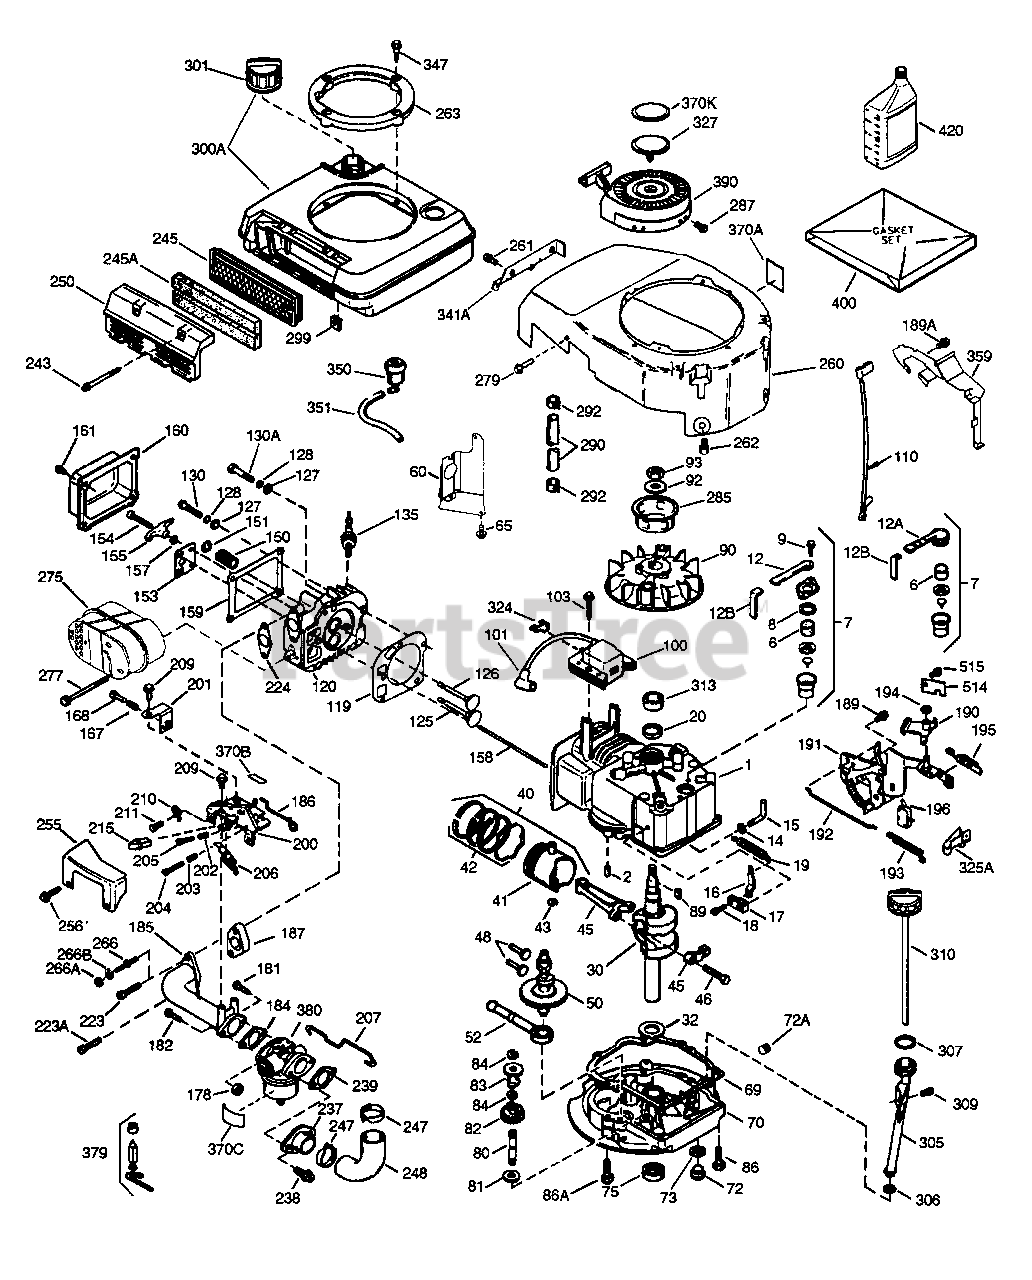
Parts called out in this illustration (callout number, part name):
1	"Cylinder (Incl. 2 & 20)
2	Dowel Pin
6	Breather Element
7	Breather Ass'y. (Incl. 6 & 12A)
12A	Breather Cover & Tube
14	Flat Washer
15	Governor Rod (Incl. 14)
16	Governor Lever
17	Governor Lever Clamp
18	Screw, Torx T-15, 8-32 x 19/64"
19	Extension Spring
20	Oil Seal
30	Crankshaft
40	Piston, Pin & Ring Set (Std.)
40	Piston, Pin & Ring Set (.010" OS)
41	Piston & Pin Ass'y. (Std.)
41	Piston & Pin Ass'y. (.010" OS) Incl. 43
42	Ring Set (Std.)
42	Ring Set (.010" OS)
43	Piston Pin Retaining Ring
45	Connecting Rod Ass'y. (Incl. 46)
46	Connecting Rod Bolt
48	Valve Lifter
50	Camshaft (MCR)
52	Oil Pump Ass'y.
60	Blower Housing Extension
65	Screw, 10-24 x 3/8"
69	* Mounting Flange Gasket
70	Mounting Flange (Incl. 72 thru 83)
72	Oil Drain Plug
75	Oil Seal
80	Governor Shaft
82	Governor Gear Ass'y. (Incl. 81)
83	Governor Spool
86	Screw, 1/4-20 x 1-7/32"
86A	Screw, 1/4-20 x 1/1/4"
89	Flywheel Key (also available in Packa ged Part #740007B)
90	Flywheel
92	Belleville Washer
93	Flywheel Nut
100	Solid State Ignition
101	Spark Plug Cover
103	Screw, Torx T-15, 10-24 x 15/16"
110	Ground Wire
119	* Cylinder Head Gasket
120	Cylinder Head
125	Exhaust Valve (Std.) (Incl. 151)
125	Exhaust Valve (1/32" OS) (Incl. 151)
126	Exhaust Valve (1/32" OS) (Incl. 151)
126	Intake Valve (Std.) (Incl. 151 & 151A )
130	Screw, 5/16-18 x 1-1/2"
130A	Screw, 5/16-18 x 2-41/64"
135	Resistor Spark Plug (RN4C) also avail able in Packaged Part #740069
150	Valve Spring
151	Valve Spring Cap
153	Push Rod Guide
154	Rocker Arm Stud
155	Rocker Arm
157	Lock Nut
158	Push Rod
159	* Rocker Arm Cover Gasket
160	Rocker Arm Housing
161	Screw, T-30, 1/4-20 x 1/2"
178	Nut & Lock Washer 1/4-28
182	Screw, 1/4-28 x 1"
184	* Carburetor Gasket
185	Intake Pipe
186	Governor Link
189A	Screw, Torx T-30, 1/4-20 x 3/8"
200	Control Bracket (Incl. 202 thru 206)
202	Compression Spring
203	Compression Spring
204	Screw, Torx T-10, 5-40 x 7/16"
205	Screw, Torx T-10, 6-32 x 41/64"
206	Terminal
207	Throttle Link
209	Screw, 10-24 x 9/16"
210	Conduit Clip
211	Screw, 10-32 x 3/8"
223	Screw, 1/4-20 x 2-25/32"
224	* Intake Pipe Gasket
238	Screw, 10-32 x 43/64"
239	* Air Cleaner Gasket
243	Screw, M-5 x 0.8-6g x 2-7/16"
245	Air Filter (also available in Package d Part #740013B)
250	Air Filter Cover
260	Blower Housing
261	Screw, T-30, 1/4-20 x 1/2"
262	Screw, 1/4-20 x 1/2"
266A	Nut & Lockwasher, 1/4-20
275	Muffler
277	Screw, 1/4-20 x 2-47/64"
279	Screw, 10-32 x 1/2"
285	Starter Cup
287	Screw, 8-32 x 21/64"
290	Fuel Line (8.62")
292	Fuel Line Clamp
301	Fuel Cap
305	Oil Fill Tube
306	* "O" Ring
307	"O" Ring
309	Screw, 10-32 x 1/2"
310	Dipstick
341A	Blower Housing Support Bracket
359	Starter Guard
370A	Lubrication Decal
370C	Decal - Primer 5X with Hand
380	Carburetor (Incl. 184)
390	Rewind Starter (NOTE: This engine co uld havbeen built with 590739 starter ).
400	Gasket Set (OVRM120 w/Silicon Flange Gasket)n notes)
420	SAE 30 4-Cycle Engine Oil (Quart)
